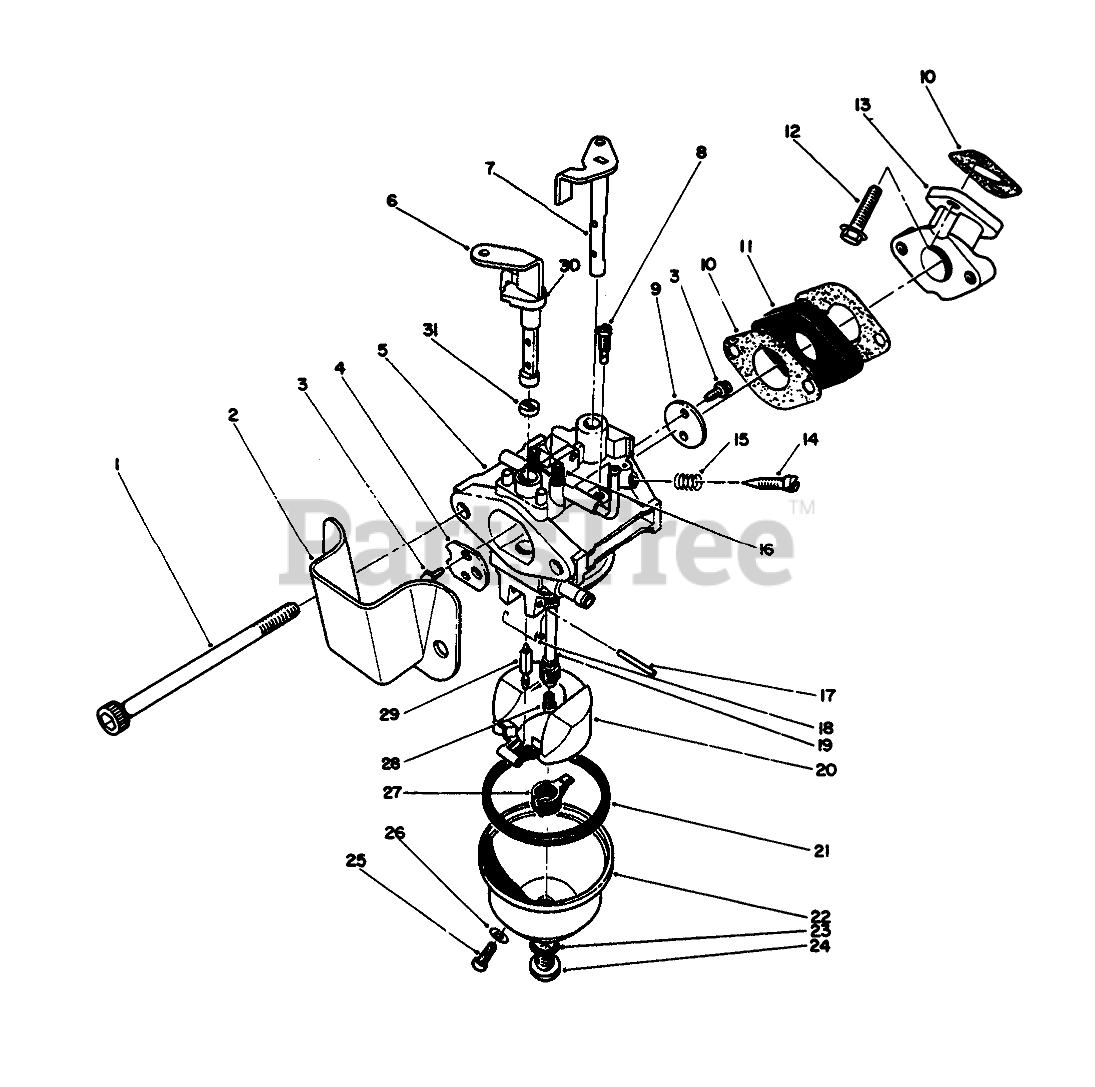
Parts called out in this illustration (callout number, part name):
2	SPIT CUP
3	Screw
4	VALVE
5	Body-Carburetor
6	Shaft-Choke (Incl. Ref. #30 & 31)
7	SHAFT
9	VALVE
10	Gasket-Carburetor
11	CARB INSULATOR
13	MANIFOLD
14	ADJUSTER
15	SPRING-PILOT SCREW
16	SPRING
17	PIN-HINGE
18	TORSION SPRING
19	MAIN NOZZLE
20	FLOAT
21	FLOAT BOWL GASKET
23	GASKET
24	SCREW
25	SCREW
26	GASKET
27	SPACER
28	MAIN JET
29	NEEDLE
30	UPPER CHOKE RING
31	LOWER CHOKE RING
